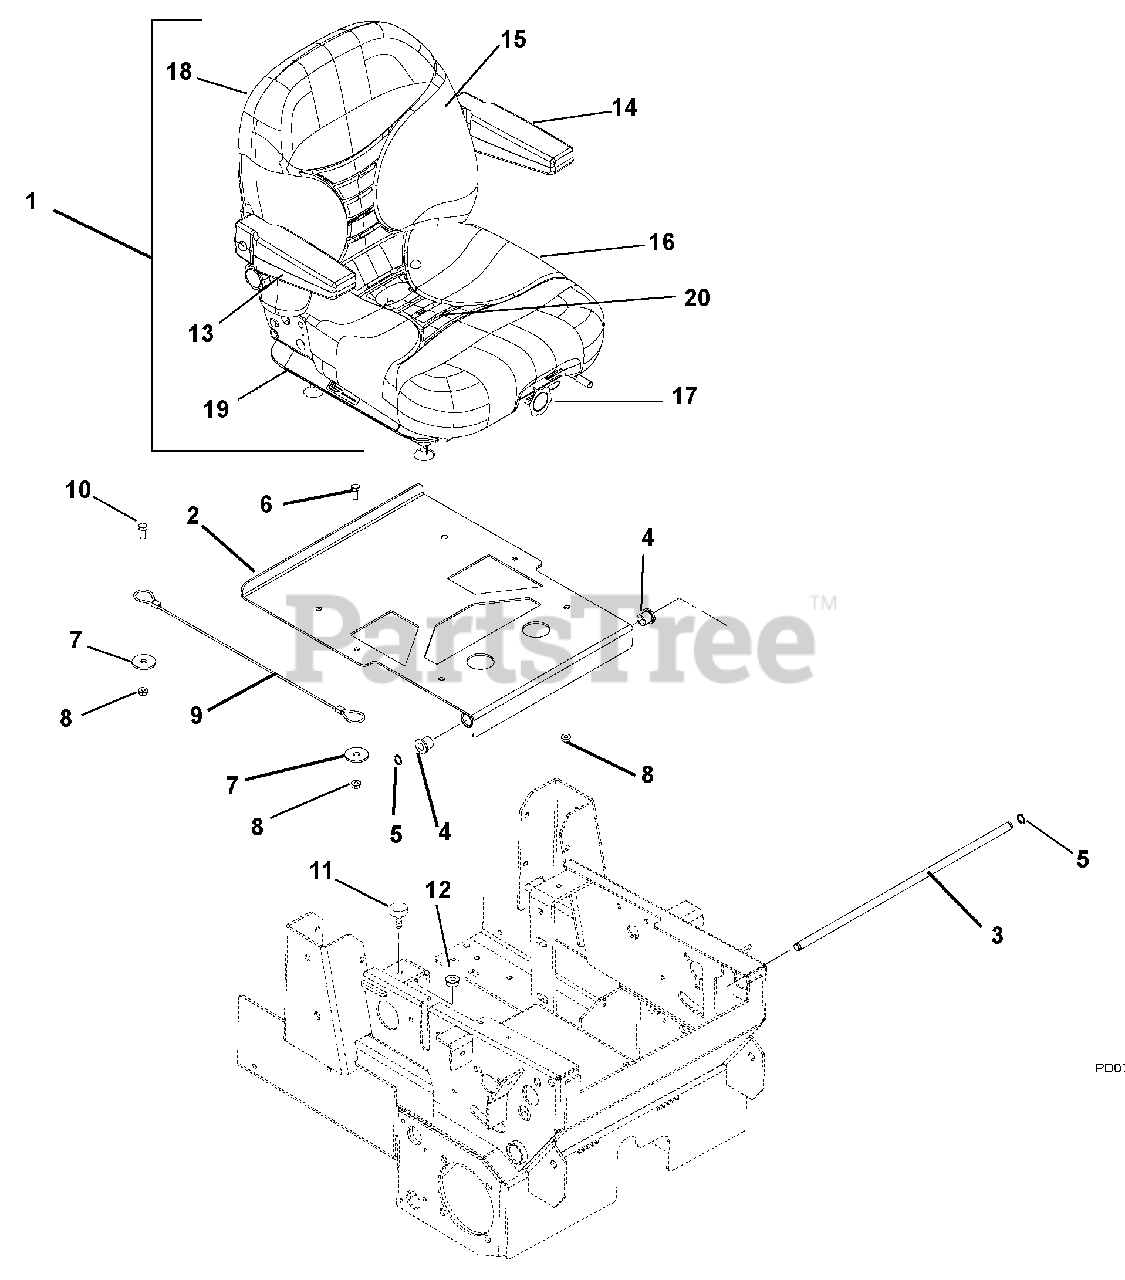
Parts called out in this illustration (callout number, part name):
1	Seat, Gray Suspension
2	Plate, Seat Pivot
3	Rod, Seat Pivot (Outfront)
4	Bushing, Flange .515 x .750 x .745 x 1.00 Nylon
5	Ring, Retaining External .500 x .050
6	Bolt, Hex .31-18 x .75 Grade 5
7	Washer, Flat Steel .344 x 1.125 x .135
8	Nut, .31-18 Nyloc Flange
9	Cable, Seat Prop
10	Bolt, Round Head Square Neck .31-18 x 1.00 Grade 5
11	Bumper, Rubber
12	Nut, Spin Lock Flange .312-18
13	Kit, Right Hand Armrest Assembly
14	Kit, Left Hand Armrest Assembly
15	Kit, Back Cushion, Light Gray
16	Kit, Seat Cushion, Light Gray
17	Kit, Seat Knobs
18	Kit, Seat Back
19	Kit, Seat Slides
20	Kit, Seat Spring and Saddle
